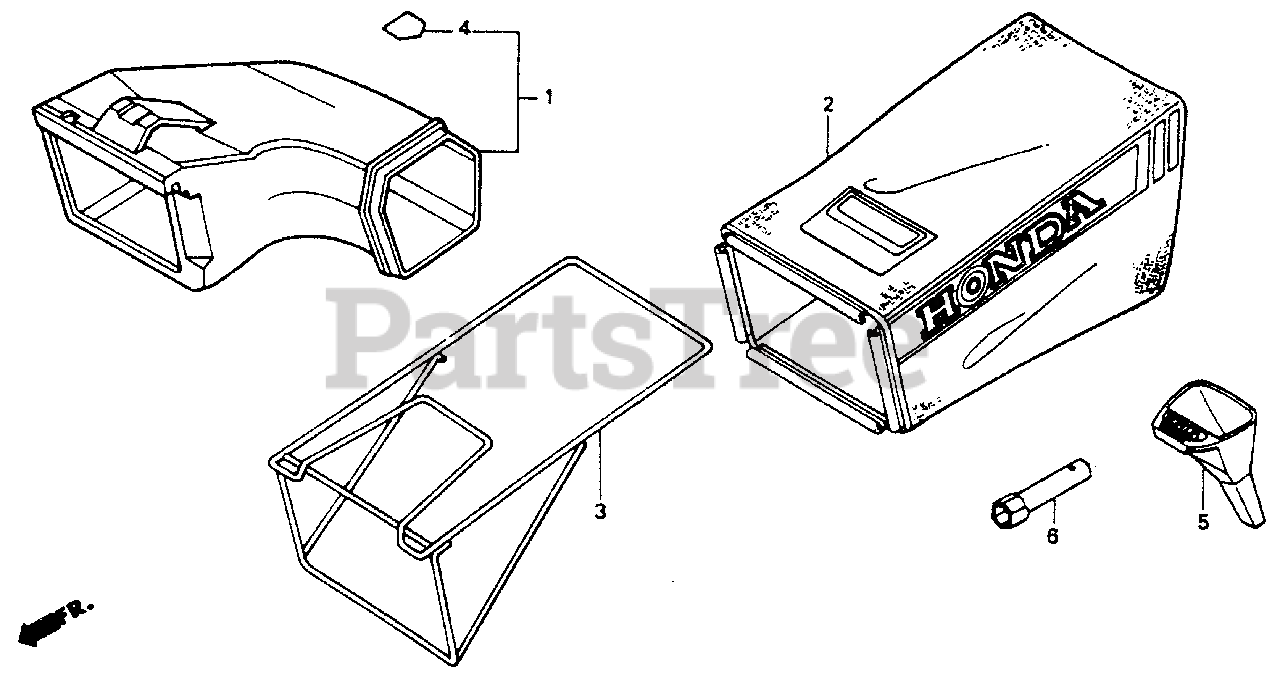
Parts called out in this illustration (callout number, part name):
1	CHUTE KIT, SIDE DISCHARGE
2	FABRIC, GRASS BAG
3	FRAME, BAG
4	LABEL C, HOUSING CAUTION
5	FUNNEL, OIL
6	WRENCH, BOX (P21)
